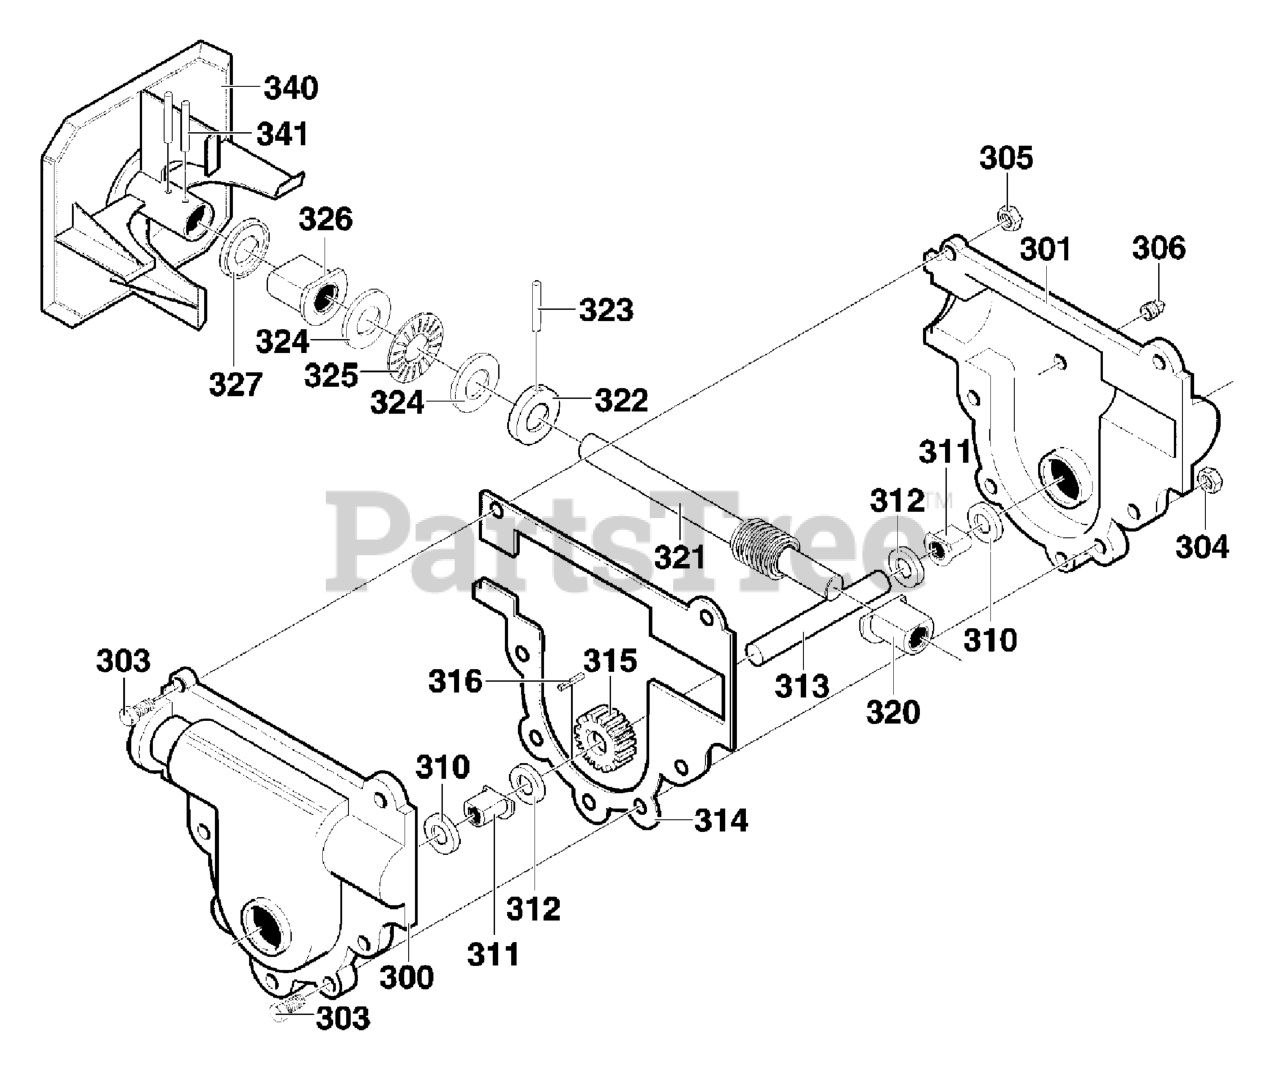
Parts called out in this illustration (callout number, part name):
300	CASE, GEAR, RH
301	CASE, GEAR, LH
303	SCREW,1/4-20X.75
304	NUT,1/4-20
305	NUT, 1/4-20 HEXKEPS
306	SCREW, 3/8-16 x 0.50
310	SEAL, OIL
311	BEARING, FL
312	WASHER, FLAT
313	SHAFT, AUGER OUTPUT
314	GASKET, GEAR BOX
315	WORM GEAR
316	KEY, WOODRUFF #61
320	BRNG, FL
321	SHAFT, AUGER INPUT
322	COLLAR, THRUST
323	PIN, SPRING
324	WASHER, FLAT
325	BRNG, ROLL
326	BRNG, FL
327	SEAL, OIL
341	PIN, SPRING
